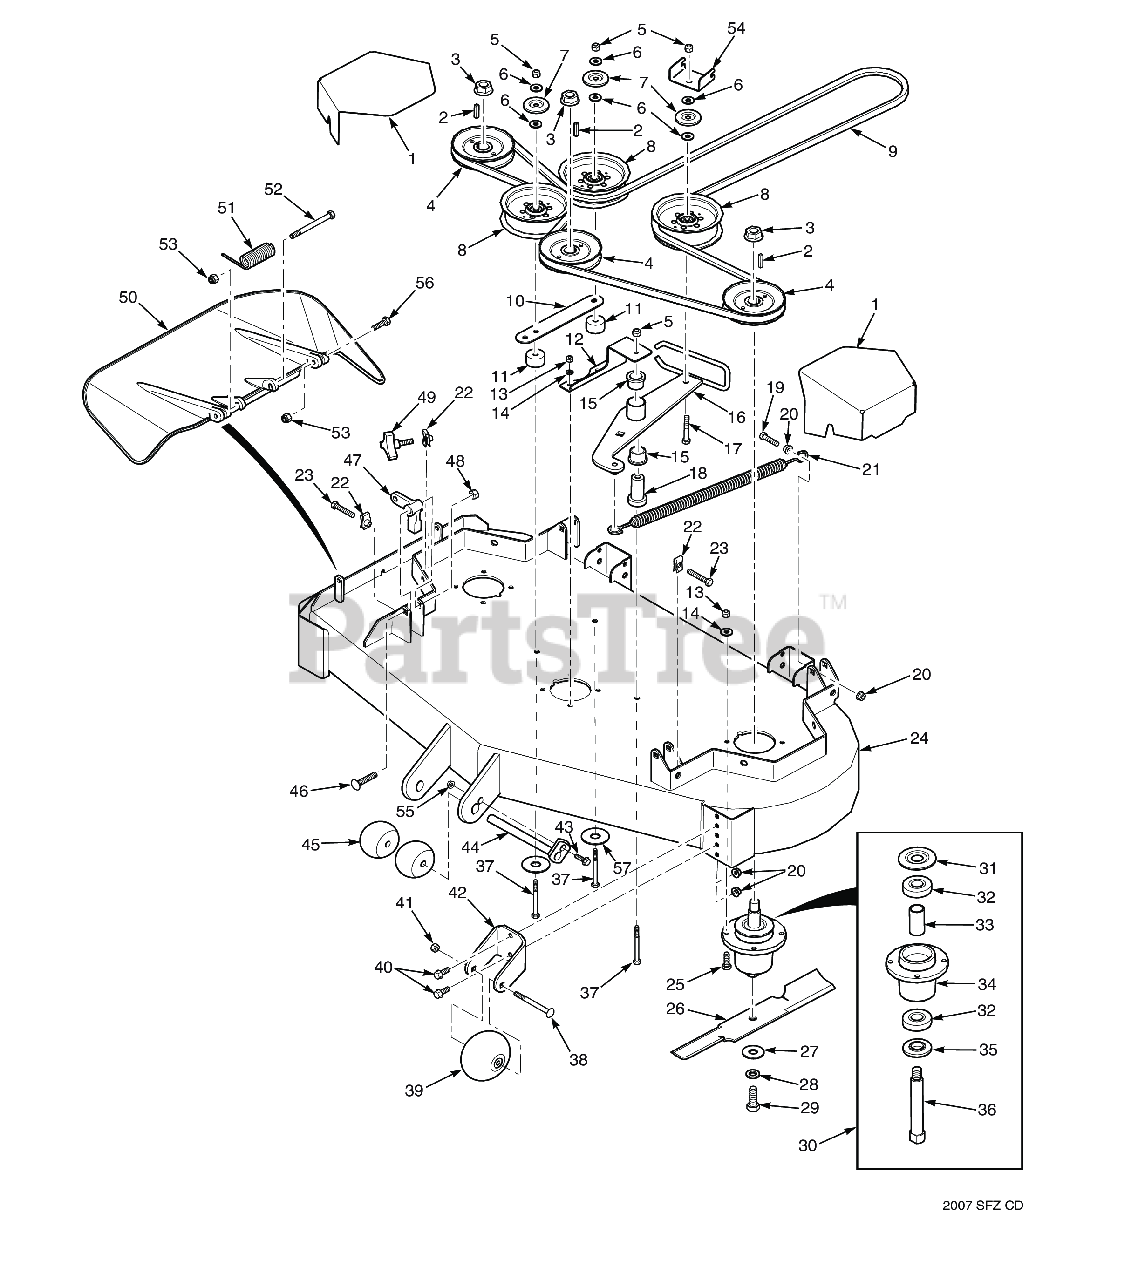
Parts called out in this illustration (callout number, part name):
1	Belt Cover
2	Key, 1/4 x 1/4 x 1.25" Pulley Mtg.
3	Nut, 3/4-16 Spriral Lock
4	Pulley, 5.13" OD - 25mm Bore
4	Pulley, 5.73" OD - 25mm Bore
5	HEX NUT, ELASTIC STOP LOCK, 3/8-16
6	Flatwasher, 3/8 (.391 x .938 x .105 HD) Grade 8
7	Quick Pin, 5/16" Dia.
8	Pulley, 5" Idler
9	Belt, Cutter Deck
10	Brace, Pulley
11	Spacer, Idler Pulley
12	Support, Idler Pivot - 48
12	Support, Idler Pivot - 52
13	Lock Nut, 5/16-18 Elastic Stop Grade 8
14	Lockwasher, 5/16 (.317 x .586 x .078) Helical Spring
15	Bearing, Plastic
16	Idler Arm (incl. item #15)
17	Capscrew, Hex Head 3/8-16 x 2-1/2"
18	Pivot, Idler
19	Bolt, Hex Head 3/8-16 x 1-1/2" Grade 8 Black
20	NUT, 3/8-16 SERRATED FLANGE HEX HEAD
21	Spring, Cutter Deck Idler
22	U-Nut, 3/8-16 (short)
23	Bolt, Hex Head 3/8-16 x 2" Special Lock
24	Cutter Deck w/Decals, SFZ48
24	Cutter Deck w/Decals, SPZ52
25	Bolt, Hex Head 5/16-18 x 1-1/2"
26	Cutter Blade, 16-1/2" (48V)
26	Cutter Blade, 18" (52V)
27	Flatwasher, 5/8-.688 x 1-3/4 x .134 HD
28	Lockwasher, 5/8" Spring
29	Bolt, Hex Head 5/8-11 x 1-1/2"
30	Spindle Assembly
31	Debris Shield
32	Bearing
33	Spacer, Bearing
34	Spindle Housing Assembly
35	Protector, Bearing
36	Shaft, Spindle
37	Bolt, Hex Head, 3/8-16 x 3-1/2"
38	Bolt, Hex Head 3/8-16 x 3-1/2"
39	Bolt, Carriage 3/8-16 x 4"
40	Capscrew, 3/8-16 x 1.0" Serrated Flange Hex Hd
41	Bolt, Hex Head 3/8-16 x 1" Ser. Flg.
42	Bracket, Anti-Scalp, (Black)
43	Bolt, Heax Head 5/16-18 x 1" (48V / 52V)
44	Bolt, Hex Head 5/16-18 x 1"
45	Wheel, Anti-Scalp
46	Bolt, Carriage 7/16-14 x 2-1/4"
47	Bolt, Carriage 7/16-14 x 2-1/4"
48	HEX LOCKNUT, ELASTIC STOP, 7/16-14
49	Knob, w/stud 3/8-16 x 1-1/4"
50	Discharge Chute Assy. SFZ48
50	Discharge Chute Assy. SFZ52
51	Spring, Discharge Chute
52	Bolt, 5/16-18 x 4-3/4" Hex Head
53	HEX NUT, ELASTIC STOP LOCK, 5/16-18
54	Bracket, Belt Guide
55	Nut, Serrated Flange 5/16-18 (Right Front Engine Mounting, Briggs and Kohler Only)
56	Bolt, Hex Head 5/16-18 x 1-1/2" - Front
57	Flatwasher, 3/8-.406 x 2.25" x .1875
